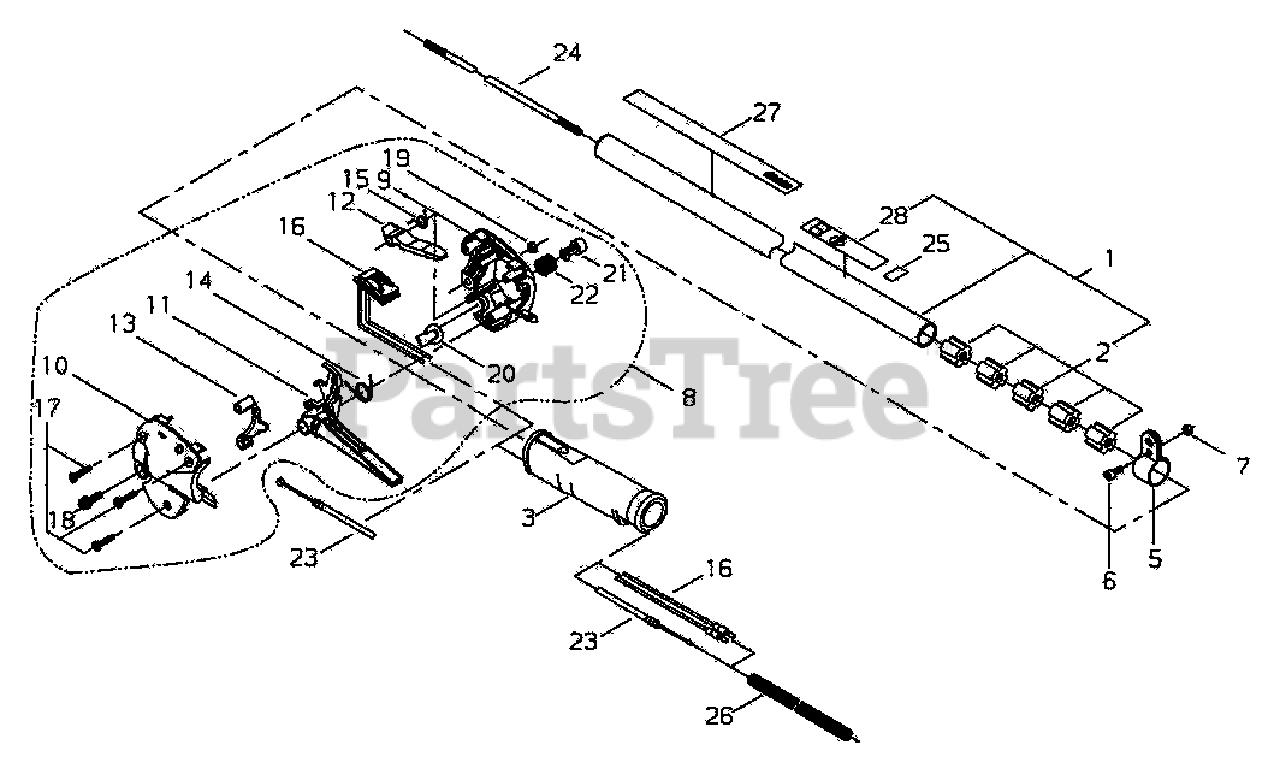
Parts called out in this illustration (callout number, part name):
1	MAIN PIPE ASSY
2	BUSHING
3	GRIP
5	BRACKET
6	SCREW - 5X12
8	THROTTLE LEVER ASSY
9	HANDLE, CONTROL - RIGHT
10	HANDLE, CONTROL - LEFT
11	TRIGGER, THROTTLE
12	LEVER, TRIGGER LOCKOUT
13	LOCKOUT, THROTTLE
14	SPRING
15	SPRING
16	SWITCH, IGNITION
17	SCREW - 4X20 -- TAPPING
18	SCREW - 5X20
19	NUT - 5
20	PLUG
21	BUTTON, THROTTLE LOCK
22	SPRING
23	CABLE, THROTTLE
24	PIPE, MAIN
25	LABEL - INSTRUCTION
26	TUBE
27	LABEL - TRADE
28	LABEL - CAUTION
